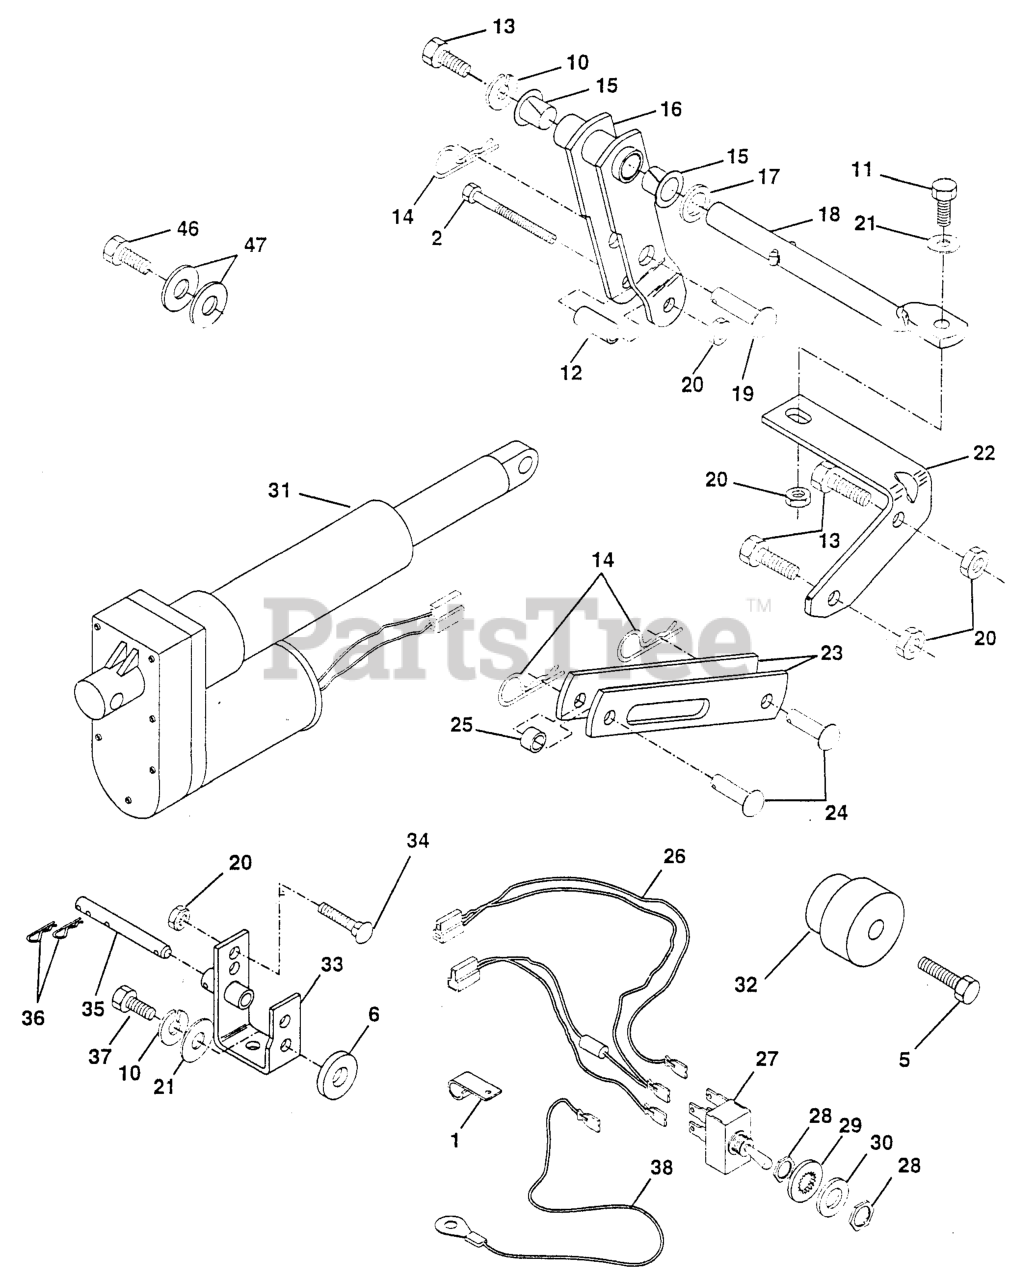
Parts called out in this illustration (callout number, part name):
1	Clip, Insulated
2	Bolt, Hex 3/8-16 x 2-1/4 Grade 5
5	Bolt. Hex 3/8-16 x 1-3/8
6	Washer 13/32 x 7/8 x 7 Ga.
10	Washer, Lock
11	Bolt, Hex 3/8-16 x 1-1/4
12	Bushing .384 x 1/2 x 1-1/4
13	Bolt, Hex 3/8-16 x 7/8
14	Spring, Retainer
16	Arm, Pivot
17	Washer 21/32 x 1 x 21 Ga.
18	Rod, Pivot Support
19	Pin, Pivot
20	Locknut 3/8-16
21	Washer 13/32 x 7/8 x 16 Ga.
22	Bracket, Pivot Rod
23	Link, Lift
24	Pin, Pivot
25	Spacer
26	Harness, Lift Kit
27	Switch, Lift
28	Nut, Switch
29	Washer, Lock Int. Tooth
30	Washer 15/32 x 3/4 x 16 Ga.
31	Electric, Actuator
32	Hub, Lever Lift
33	Bracket, Assembly Actuator, Gear Drive
34	Bolt, Carriage 3/8-16 x 1
35	Pin, Actuator
36	Spring, Retainer
37	Bolt, Hex 3/8-16 x 1
38	Wire, Ground
46	Bolt, Hex 5/16-18 x 1-1/4
47	Washer 11/32 x 1-1/2 x 10 Ga.
